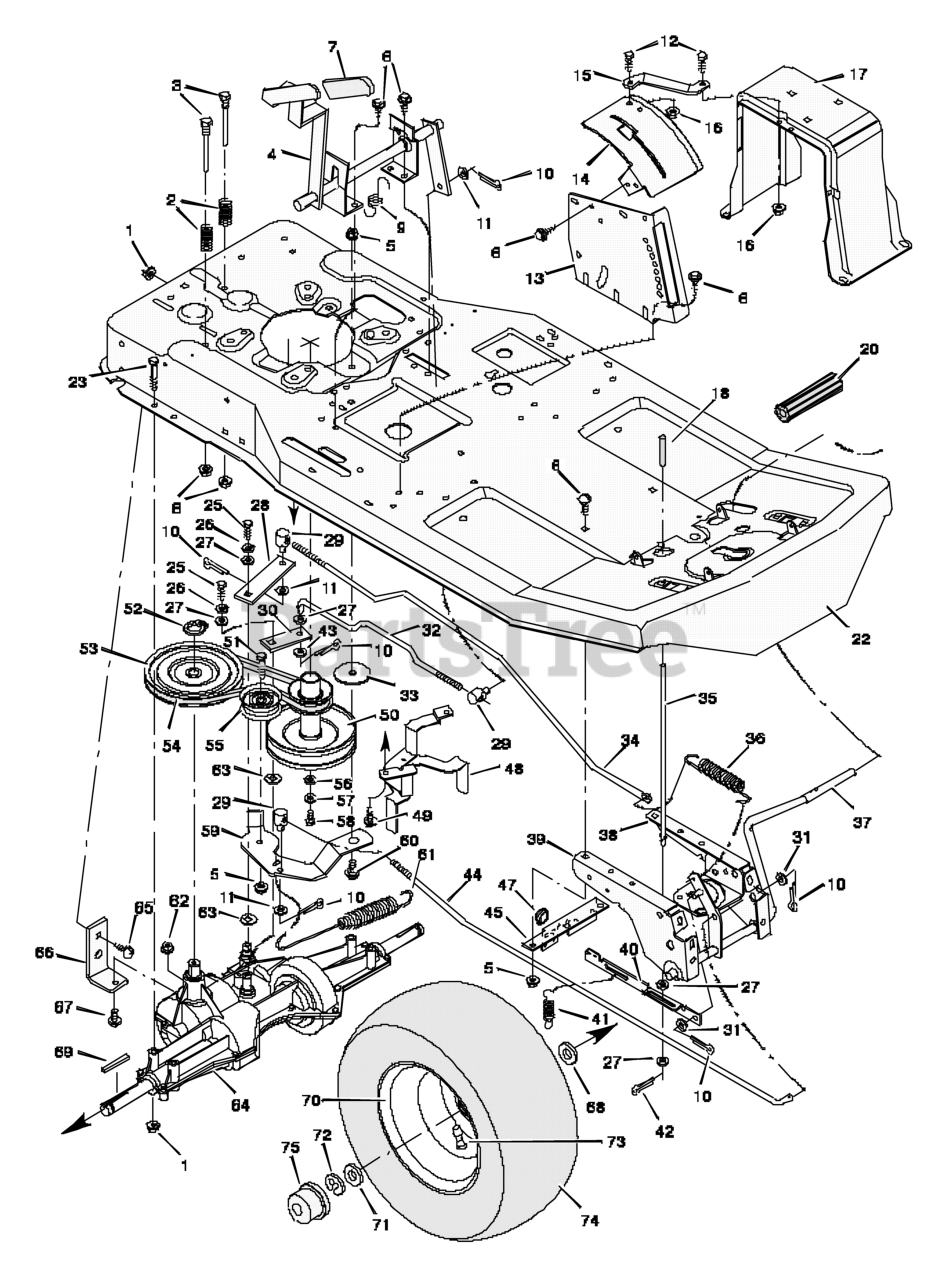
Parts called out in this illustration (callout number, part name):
1	Locknut, Flange
2	Spring, Compression
3	Guide, Belt
4	Shifter Assembly
5	Locknut, Flange
7	Grip, Shift Lever
8	Hex Nut
9	Spring, Extension
10	Pin, Cotter
11	Washer
12	Bolt, Hex
13	Plate, Index
14	Gate, Shift
15	Brace, Shift Gate
16	Locknut, Flange
17	Support, Seat
18	Grip, Parking Brake
20	Pedal, Rubber
22	Frame Assembly
23	Bolt, Hex
25	Bolt, Hex
26	Lockwasher
27	Washer
28	Yoke, Brake
29	Nut, Adjusting
30	Yoke, Shift
31	Washer
32	Rod, Shift
33	Washer, Hardened
34	Rod, Brake
35	Rod, Parking Brake
36	Spring, Extension
37	Lever, Pedal
38	Plate, Left Suspension
39	Plate, Right Suspension
40	Link, Parking Brake
41	Spring, Extension
42	Pin, Cotter
43	Washer
44	Rod, Clutch
45	Stop, Parking Brake
47	Grommet
48	Guide, Belt
50	Pulley Assembly, Stack
51	Bolt, Hex
52	Ring, Retainer
53	Pulley, Drive
54	Belt, Motion Drive
55	Pulley, Idler
57	Lockwasher
58	Bolt, Hex
59	Bracket, Idler
60	Bolt, Shoulder
61	Spring, Extension
62	Locknut, Hex
64	Transaxle, Dana Model 4450-1 **
65	Bolt, Carriage
66	Bracket, Transaxle
67	Bolt, Hex
69	Key, Square
70	Wheel & Tire Assembly
73	Valve Stem
74	Tire *
75	Hub Cap
